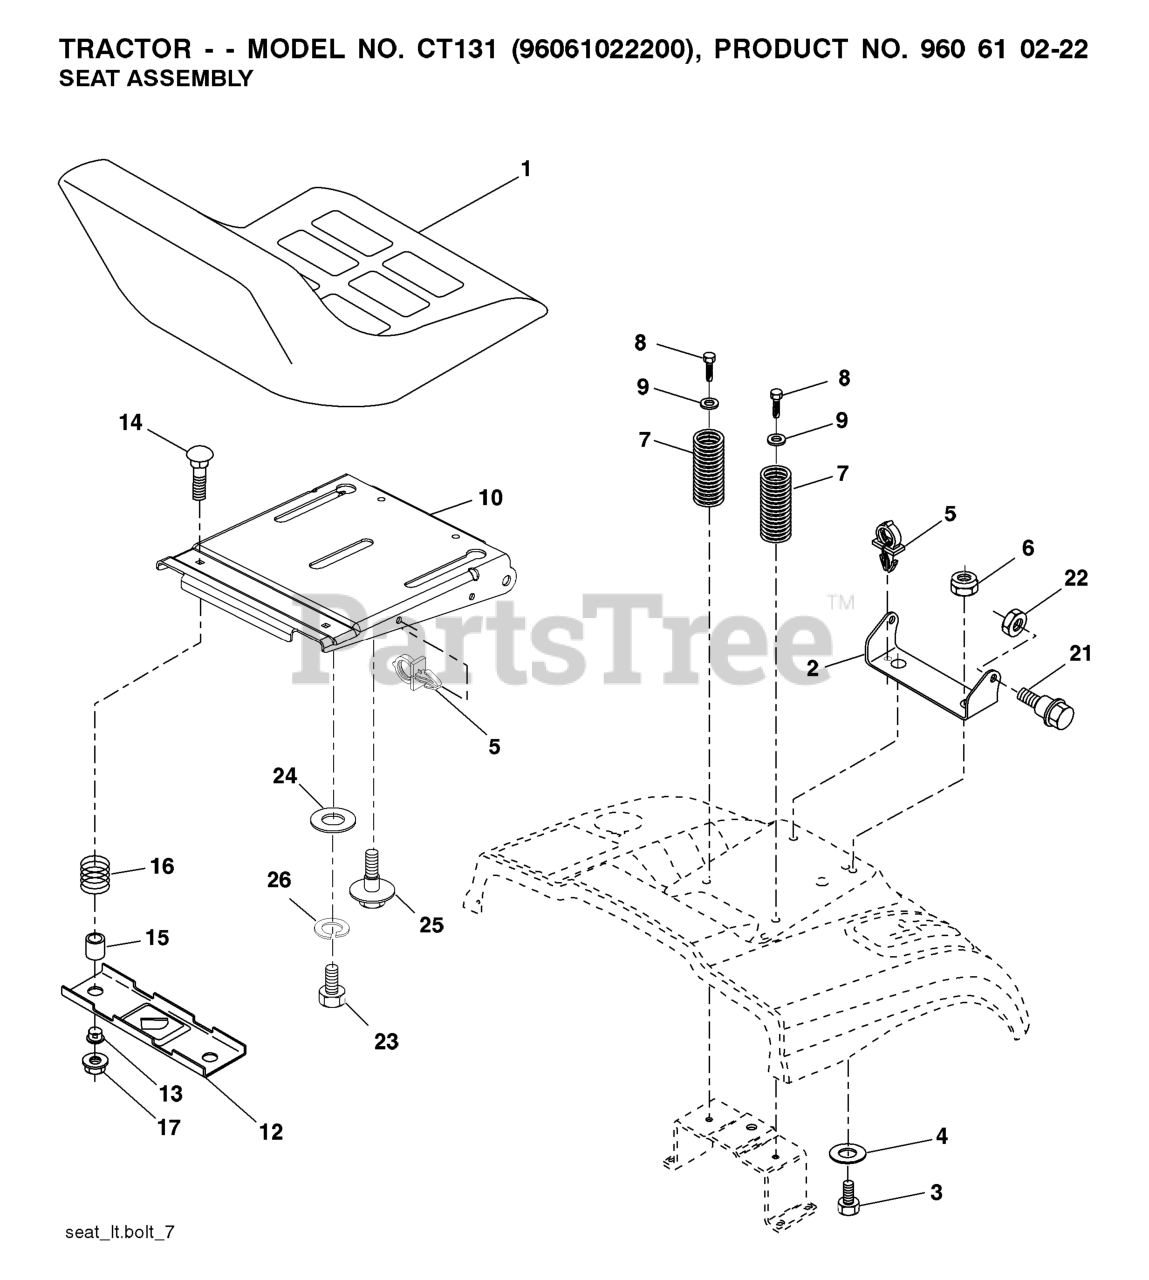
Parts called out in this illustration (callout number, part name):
1	SEAT.XG090.BLK.KB/BLT.NO-LOG
2	SEAT PIVOT BRKT
3	BOLT, HEX 3/8-16X1
6	NUT
7	SPRING COMPRESSION
8	SCREW 3/8-16X1
9	WASHER
10	PAN.ASM.SEAT.1SLOT
12	BRKT.MNTNG.SWITCH.SEAT.BLACK
14	BOLT.ROUND.HEAD.SQUARE.NECK
15	SPACER SPLIT 28X.96
17	NUT T
21	BOLT.SHOULDER.5/16-18
22	NUT.71038.31-18.HEX.NYLOCK
23	BOLT.HEX.BLACK
25	BOLT,SHOULD
26	LOCKWASHER
